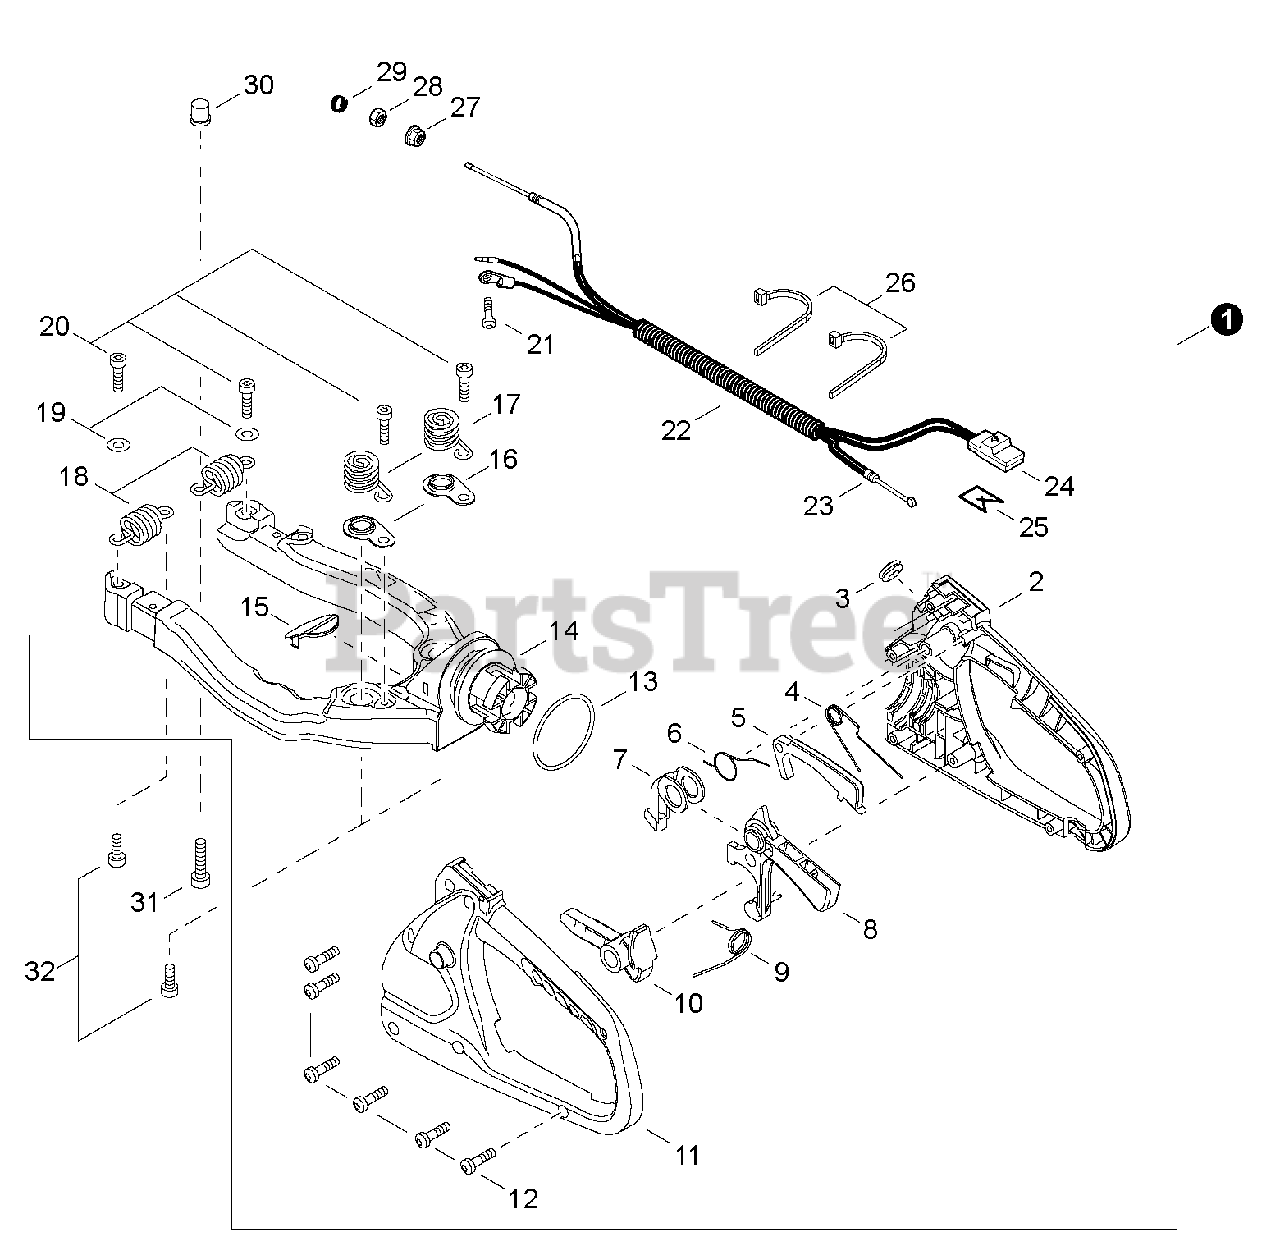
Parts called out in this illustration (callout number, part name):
1	HANDLE ASSY - REAR
2	HANDLE, REAR - RIGHT
3	GROMMET
4	SPRING, LOCKOUT
5	LEVER, TRIGGER LOCKOUT
6	SPRING, TRIGGER
7	LEVER, THROTTLE
8	TRIGGER, THROTTLE
9	SPRING, TRIGGER
10	LEVER, HANDLE RELEASE
11	HANDLE, REAR - LEFT
12	SCREW - 4X16 -- TAPPING
14	FRAME
15	COVER, HANDLE
16	HOLDER, SPRING
20	SCREW - 6X20
21	SCREW - 4X8
22	TUBE, PROTECTIVE
23	CABLE, THROTTLE
24	SWITCH, IGNITION
26	TIE, CABLE
27	NUT - 6 -- FLANGE
31	SCREW - 6X25
32	SCREW - 6
